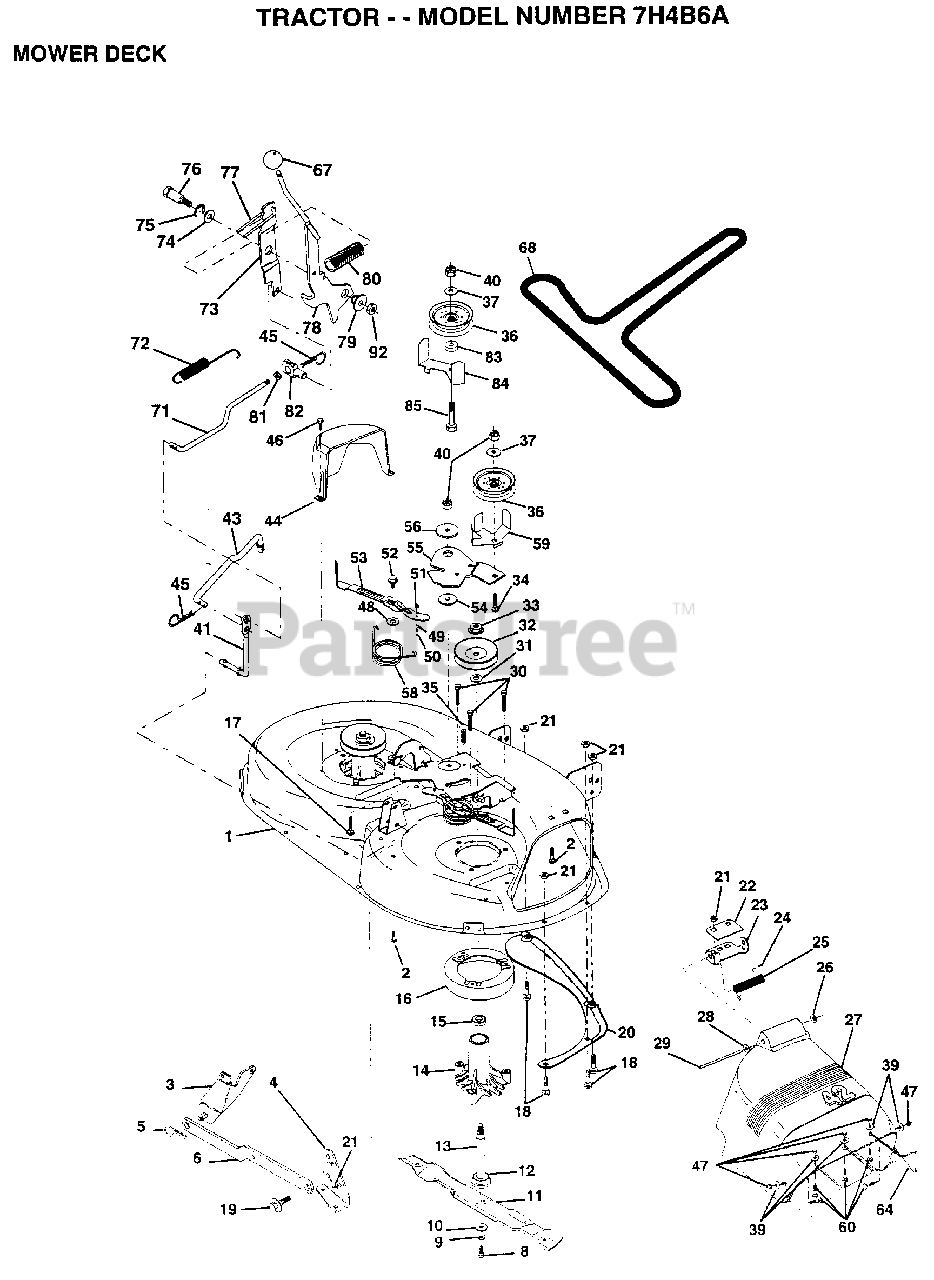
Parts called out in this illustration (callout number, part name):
1	DECK.WELD.42.
2	BOLT
3	BRKT ASM SWAY BAR
4	BRKT DECK SW BAR
8	BLADE BOLT
10	WASHER.HARD.BLADE
11	"BLADE.42"" HIPERF"
12	BEARING.BALL
14	HSG ASM MANDREL
15	BEARING
16	STRIPPER RND MWR
17	BOLT RDHD 3/8-16
18	BOLT
19	BOLT SHD 5/16-18
22	STIFFENER BRKT
23	DEFLECTOR BRKT
24	CAP-SLEEVE LT
25	SPRING TORSION
26	NUT PUSH M
27	DEFLECTOR.CLIP.TU
28	WASHER
29	HINGE ROD
31	WASHER
34	BOLT
35	XMAS TREE FASTNER
36	FLAT IDLER PULLEY
37	WASHER
41	PIVOT ROD
43	ROD CLUTCH W/NIBS
44	GUARD MAND LH BLK
45	RETAINER M
46	SCREW.1/4-20X5/8
47	ACORN NUT RB
48	HARD SMALL WASHER
50	SHOULDER BOLT
51	LOCKNUT
52	BOLT.SHLD.5/16-18
53	BRAKE PAD ARM ASM
54	HARDENED WASHER
56	SPACER RETAINER
58	SPRING TORSN BRAK
59	GUARD IDLER TUV
60	SCREW
64	GUARD.FOOTREST.42
67	KNOB T(3/8 HOLE)
68	BELT.V.T-PATH
71	ROD CLUTCH 38/42
72	RETURN SPRING
73	CLUTCH ARM SECOND
74	WASHER
75	RING
76	SHOULDER BOLT
77	SPRING KEEPER
79	BUSHING
81	NUT
82	TRUNION ADJ
83	WASHER
85	BOLT RDHD 3/8-16
92	NUT
